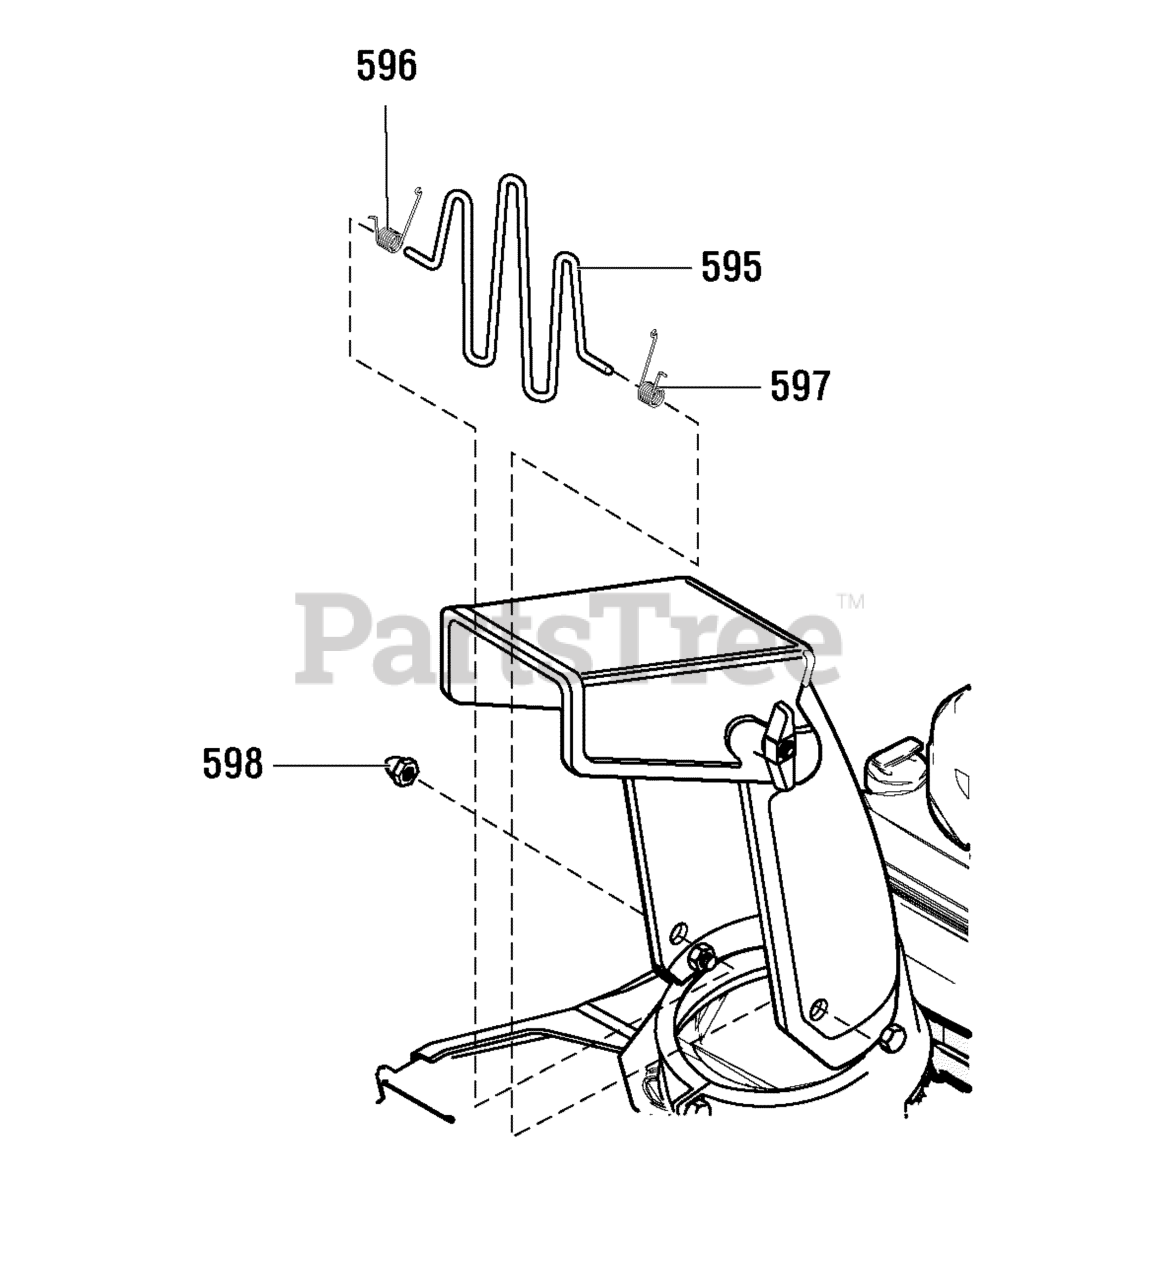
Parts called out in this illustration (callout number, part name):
595	GUARD, WIRE CHUTE
596	SPRING, TORSION
597	SPRING, TORSION
598	NUT, ACORN
